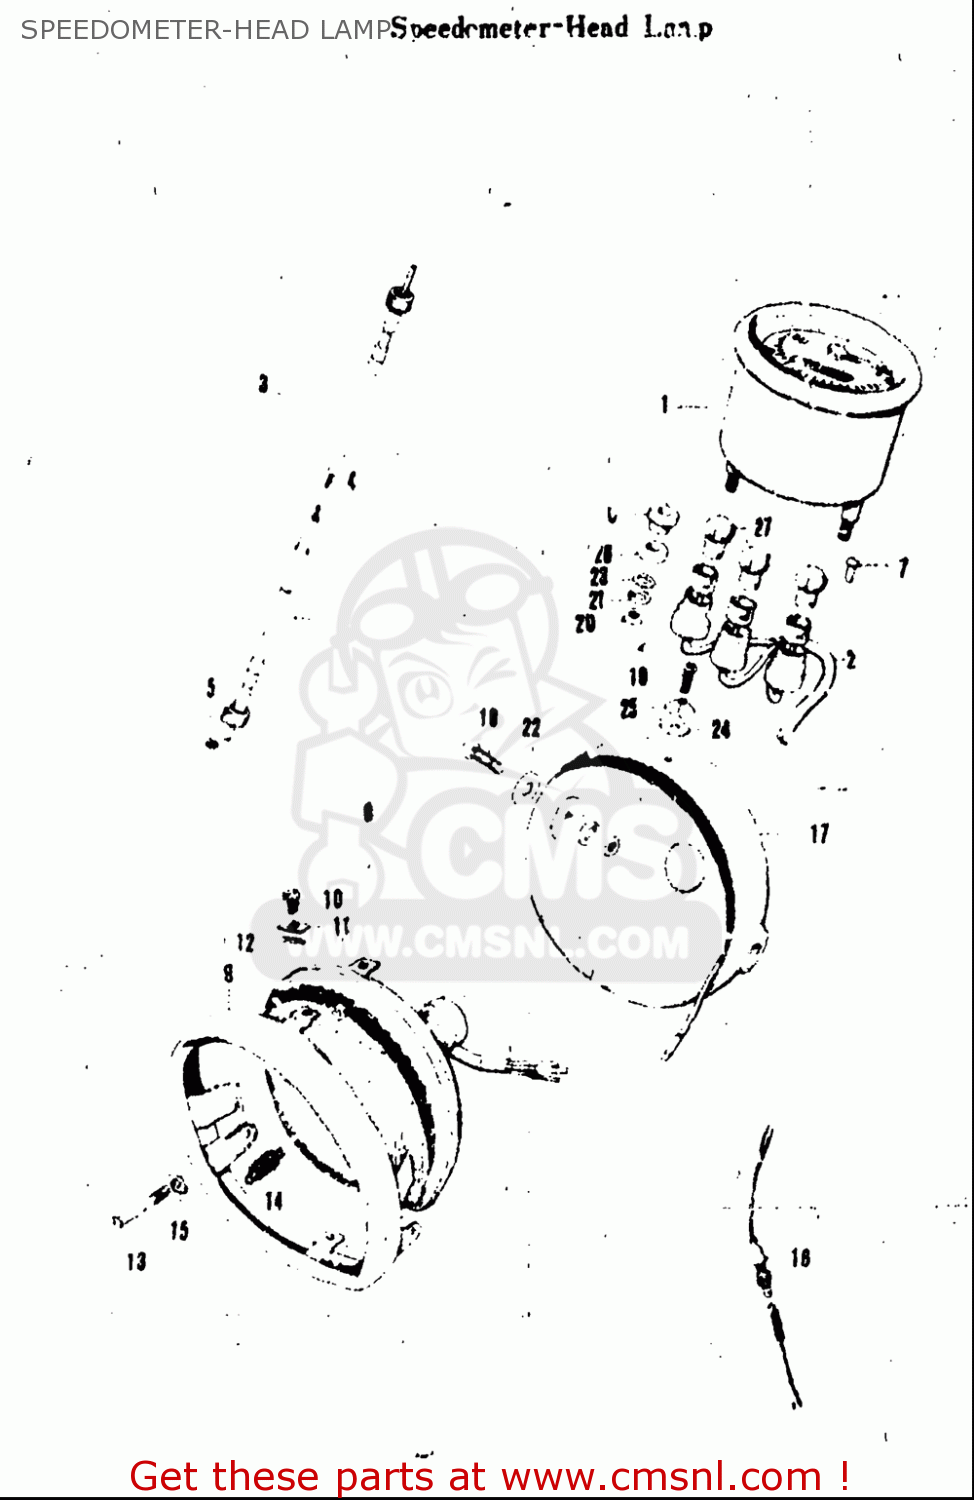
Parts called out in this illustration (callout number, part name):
5	SEAL,OIL METER CABLE
11	NUT
13	SCREW,HEADLAMP ADJUST
14	SPRING,HEADLAMP ADJUST
15	NUT,HEADLAMP ADJUSTER
18	BOLT
19	SCREW
20	NUT
21	WASHER,LOCK
22	WASHER
23	WASHER (5.5X18X1.6)
24	WASHER(4X12.5X0.3)
25	WASHER
26	CUSHION
